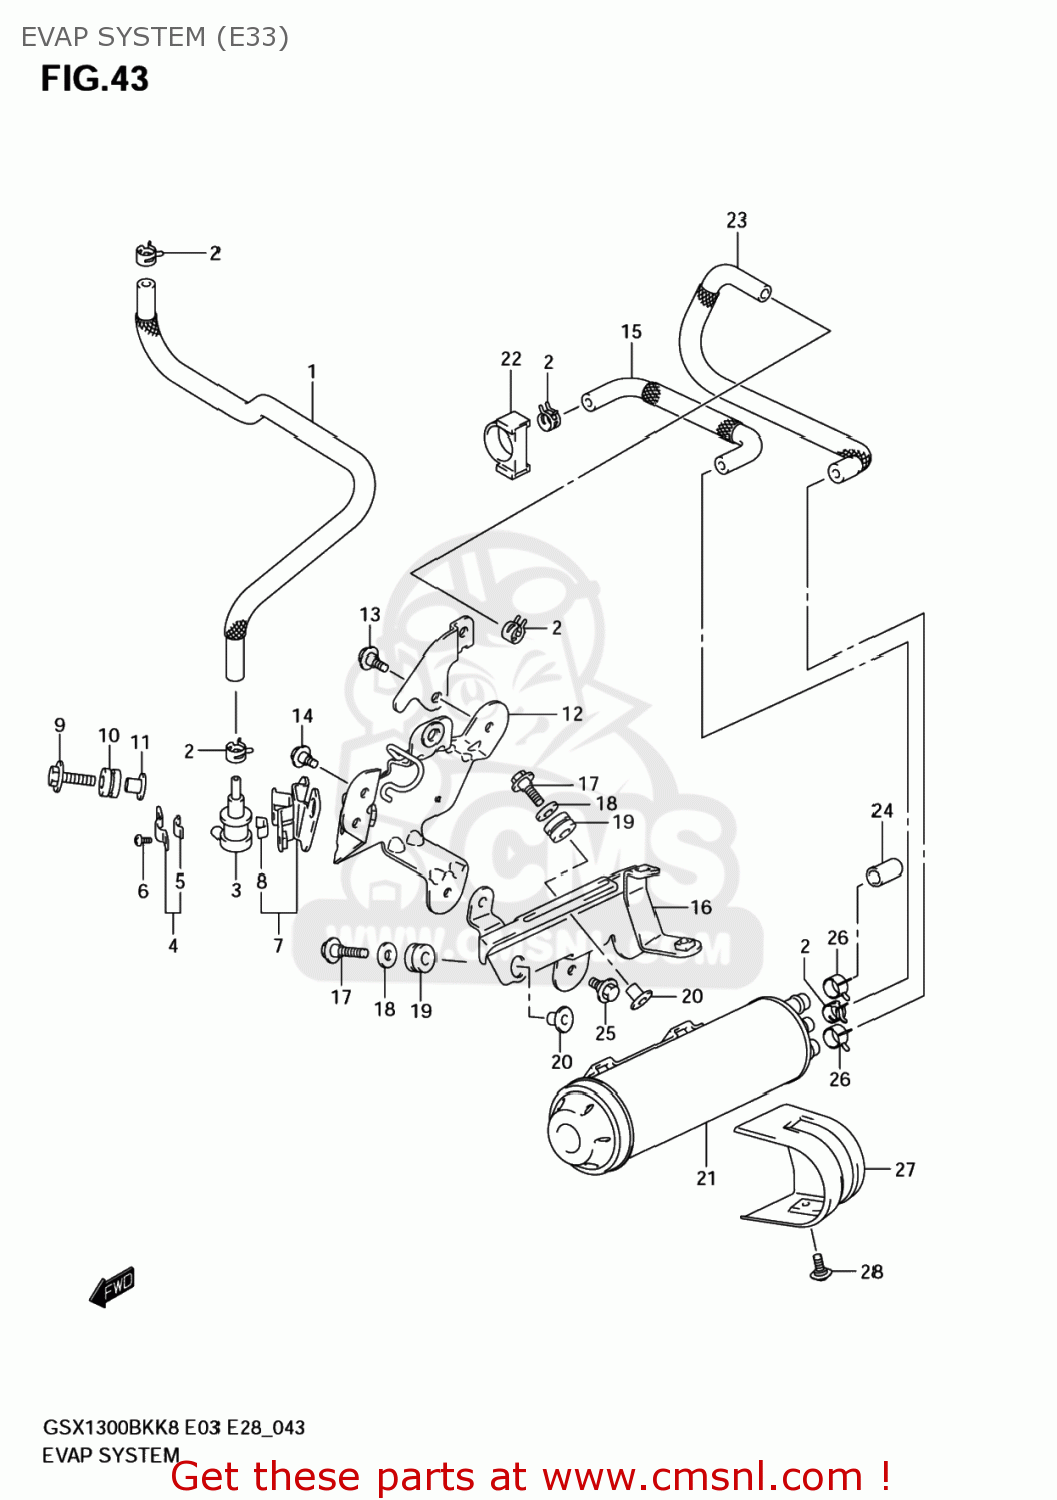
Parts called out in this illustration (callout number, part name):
1	HOSE,FUEL TANK & BRTHR VALVE
2	CLIP
3	VALVE,FUEL TANK BREATHER
4	PLATE,FUEL TANK BREATHER NO.2
5	CUSHION
6	SCREW
7	BRACKET,BREATHER VALVE
8	CUSHION
9	BOLT(6X25)
10	CUSHION
11	WASHER
12	BRACKET,EVAP SYSTEM
13	BOLT
14	BOLT
15	HOSE,2 WAY & BREATHER VALVE
16	BRACKET,CANISTER
17	BOLT
18	WASHER(6.5X16X3.2)
19	CUSHION
20	WASHER
21	CANISTER SET
22	CUSHION,CHECK VALVE
23	HOSE,CSTR & PURGE VALVE
24	CAP,OD:11.5
25	BOLT
26	CLIP
27	COVER,CANISTER
28	SCREW(5X13)
